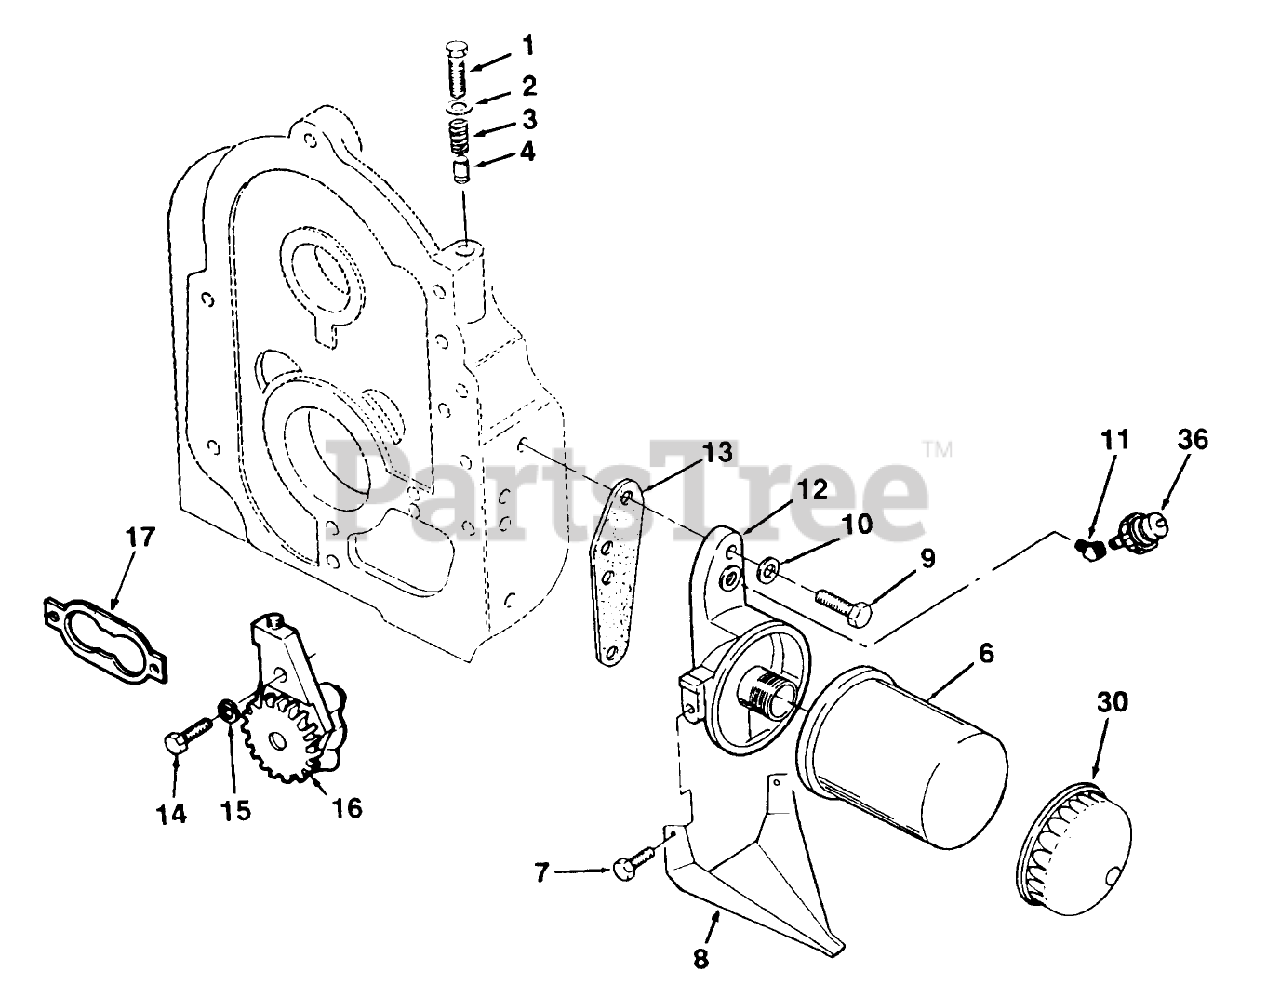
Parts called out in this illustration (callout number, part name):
1	HX HD CAPSCREW
2	WASHER
3	SPRING
4	PLUNGER
6	FILTER-OIL
7	SCREW-HH
8	DRAIN-OIL FILTER
9	HHCS 5/16-18 X 1
10	WASHER
11	ELBOW-45 DEG
12	ADAPTER-OIL FILTER
13	GASKET-OIL FILTER ADAPT
14	SCREW - CAP HEX HEAD
15	WASHER-FLAT
17	GASKET KIT
30	WRENCH-OIL FILTER
36	Switch-Oil Pressure
